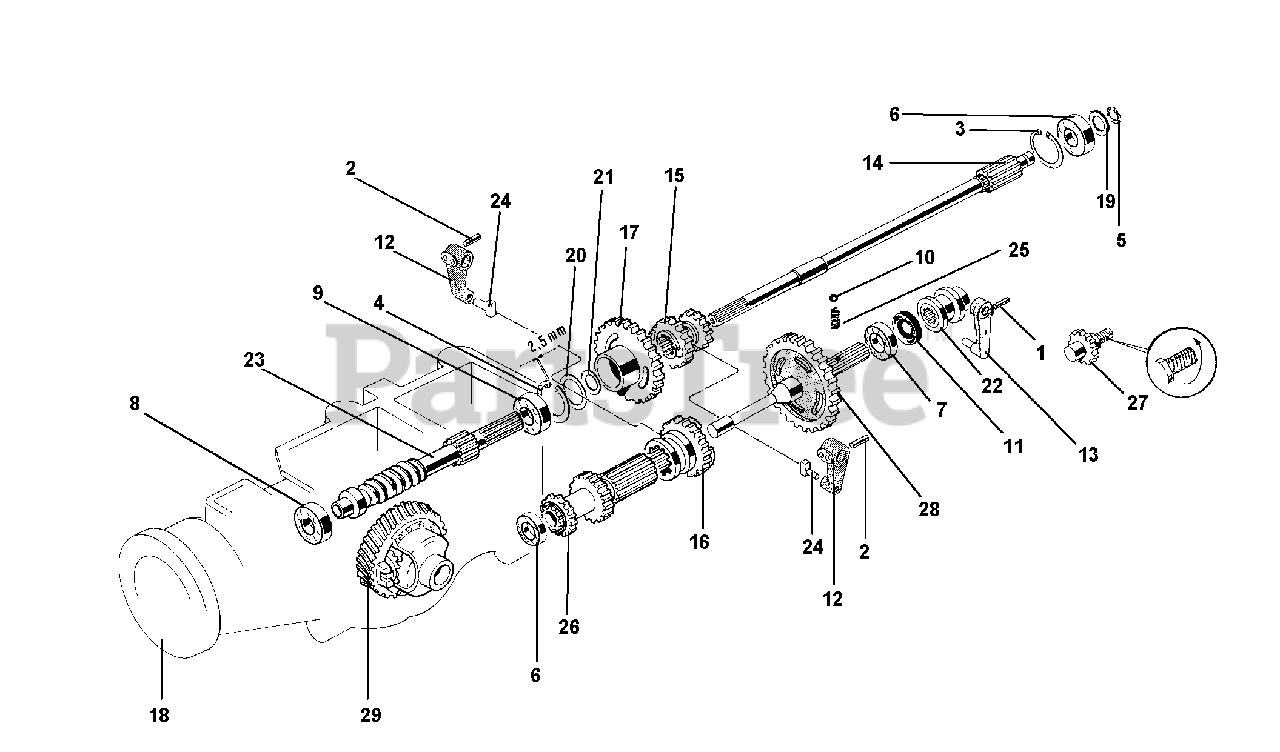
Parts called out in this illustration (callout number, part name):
1	LOCKING PIN 4 X 20 SPIRAL
2	LOCKING PIN 4 X 24 SPRIAL
3	INSIDE CIRCLIP DIAM. 35
4	INSIDE CIRCLIP DIAM. 52
7	BEARING 20 X 47 X 14 6204
8	BEARING SKF 25 X 52 X 15 6205
10	BALL 1/4 RIV RB-6.35
11	SEAL, OIL 20 X 35 X 7 STANDARD
12	LEVER, SPEED CHG SLDG GR
13	SLIDE LEVER
14	CLUTCH SHAFT FOR REVERSER
15	DOUBLE SLIDER
16	REVERSER SLIDER
17	WHEELS FIRST SPEED
18	GEARBOX 745/606-605
19	WASHER, 15.1 X 25 X 2
21	WASHER 25 X 32 X 2 C-72
25	SPRING D6.2 X 15
27	REVERSER PIN
28	P.T.O. SHAFT
29	DIFFERENTIAL 737
